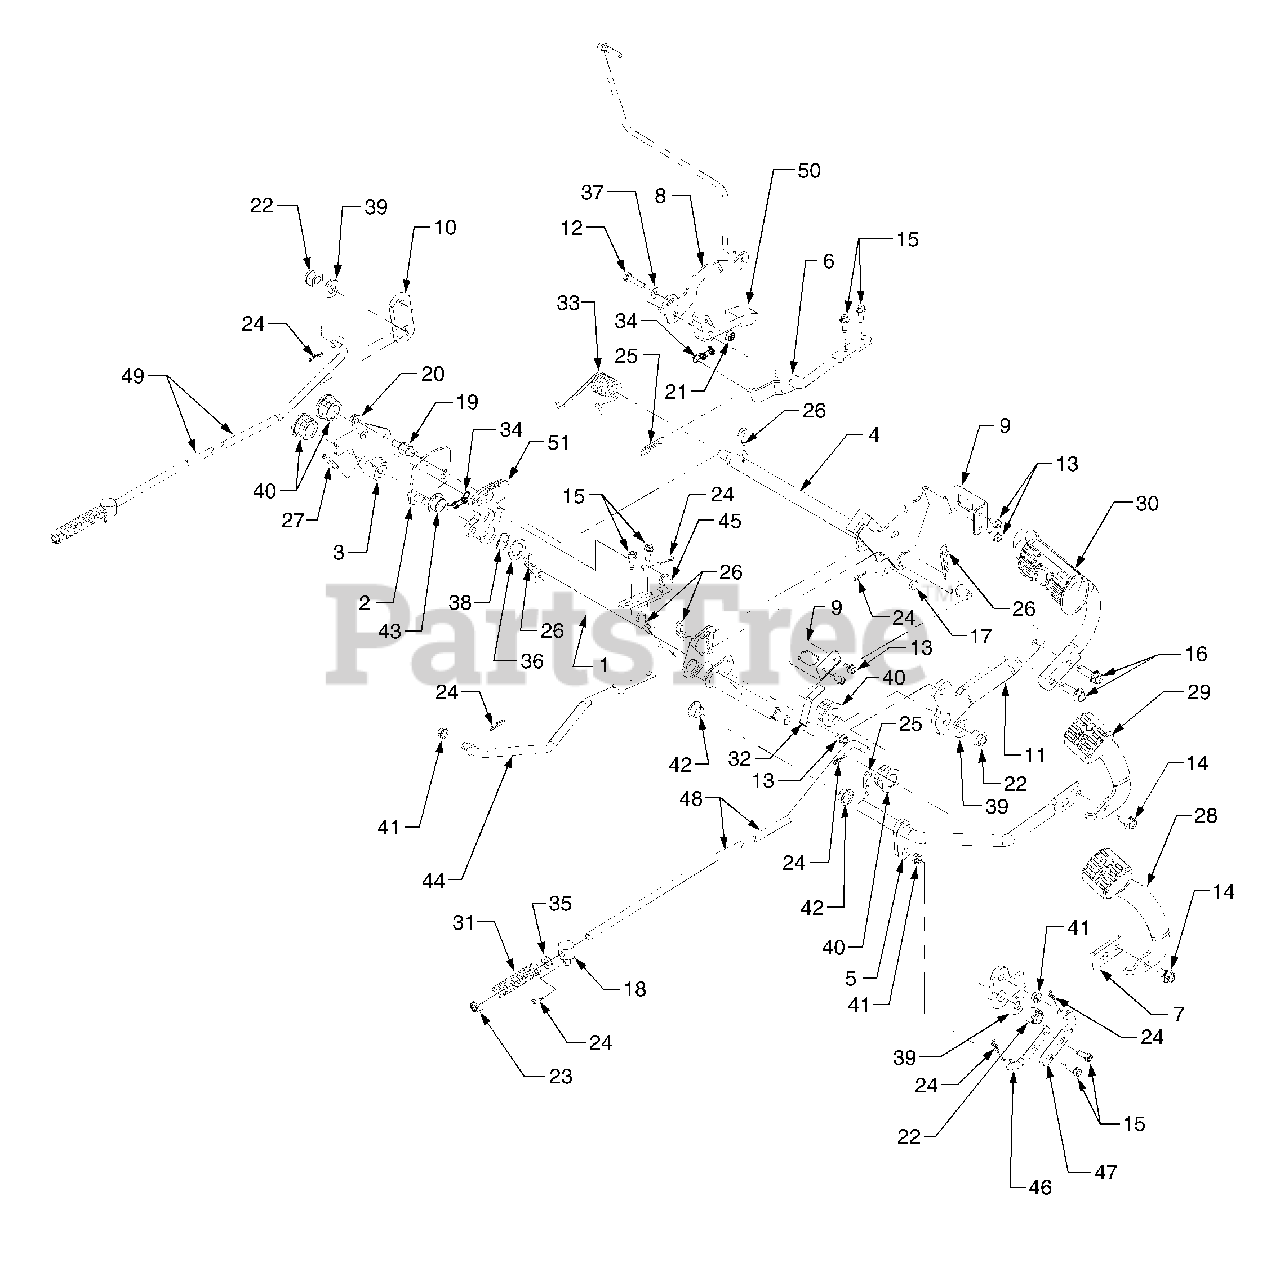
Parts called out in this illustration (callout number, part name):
1	Shaft Assembly, Pedal
2	Plate, Disengagement
4	Shaft Assembly, Brake
5	Shaft Assembly, Reverse
6	Rod Assembly, Cruise
7	Link, Pedal Mounting
8	Bracket, Rod Adjust
9	Bracket, Switch
10	Lever, Brake
11	Link, Brake Pedal
12	Screw, Hex Cap, 1/4-20 x 1.25 GR5
13	Screw, Hex Wash. Hd. Tapp 1/4-20 x .5
14	Screw, Hex Wash. Hd. Tapp 3/8-16 x .75
15	Screw, Hex Wash. Hd. Tapp 1/4-20 x .75
16	Screw, Hex Wash. Hd. Tapp 3/8-16 x 1.25
17	Pin, Clevis, 3/8 x 2.015
18	Ferrule, Adjust.
19	Stud, Actuator
20	Nut, Hex Flange Lock, 5/16-18
21	Nut, Hex Flange Lock, 1/4-20
22	Nut, Hex Insert Lock, 1/2-20
23	Nut, Hex Lock, 3/8-24
24	Pin, Internal Cotter
25	Pin, Internal Cotter
26	Pin, Internal Cotter
27	Pin, Spiral Spring, .25 x 1.5
28	Pedal, Forward
29	Pedal, Reverse
30	Pedal, Brake
31	Spring, Compression
32	Spring, No Cut Reverse
33	Spring, Torsion
34	Spring, Extension, .380 OD x 1.44
35	Washer, Flat, .406 x .75 x .063
36	Washer, Flat, .79 x 1.24 x .060
37	Washer, Flat, .25 x .62
38	Washer, Wave, .785 x 1.0 x .012
39	Washer, Flat, .531 x 1.06 x .134
40	Bearing, Hex Flange
41	Bearing, Flange
42	Bearing, Flange
43	Bearing, Flange
44	Rod, Rear Control
45	Rod, Front Control
46	Rod, Rear Connecting
47	Rod, Front Connecting
48	Rod, Brake RH
49	Rod, Brake LH
50	Cruise Latch
51	Plate, Cruise
